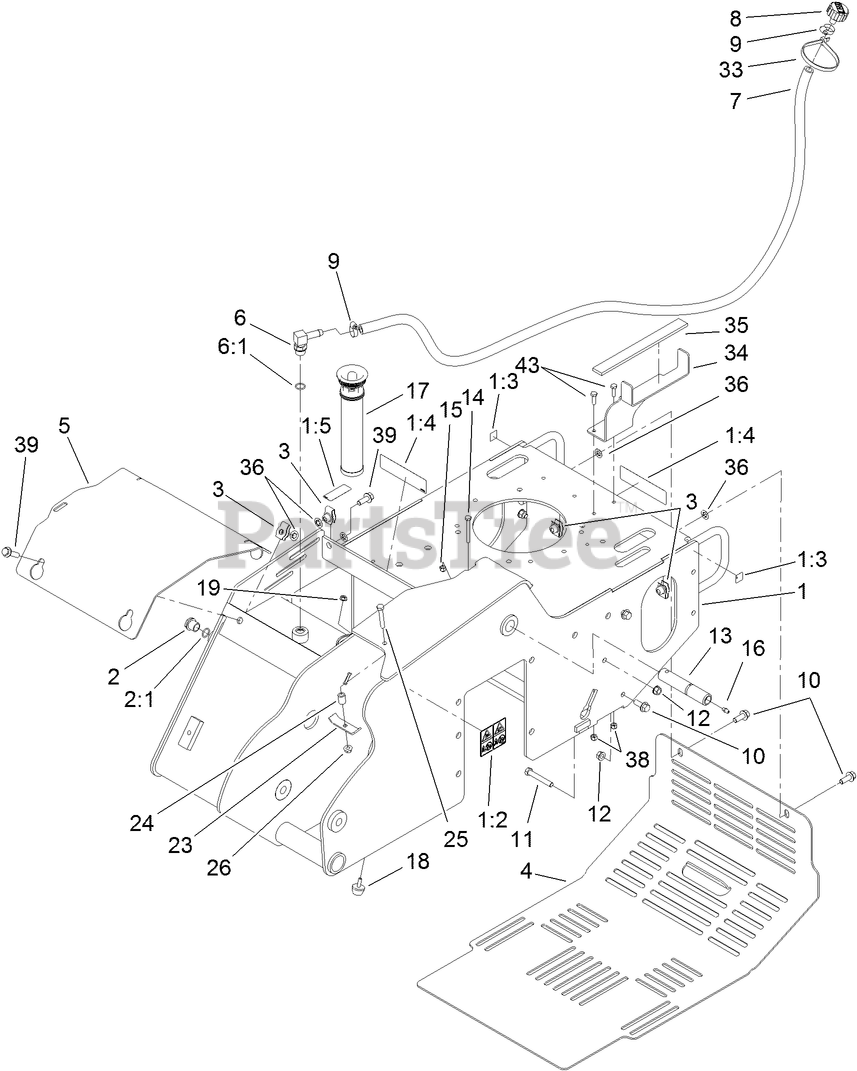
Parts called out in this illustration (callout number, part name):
1	MAIN FRAME ASM
1:2	DECAL-WARNING
1:3	DECAL-POINT, LIFT
1:4	DECAL-DANGER
1:5	DECAL-OIL, HYD
2	SIGHT GLASS ASM
2:1	O-RING
3	NUT-CLIP, U
4	COVER-REAR
5	PLATE-COVER, FRONT
6	FITTING-ELB 90
6:1	O-RING
7	HOSE-BREATHER
8	BREATHER
9	CLAMP-HOSE
10	SCREW-HHF
11	SCREW-HH
12	NUT-FLANGE
13	PIN-PIVOT
14	SCREW-HH
15	NUT-LOCK, NI
16	FITTING-GREASE
17	IN-TANK FILTER ASM
18	BUMPER
19	NUT-HF
23	BRACKET-CLAMP
24	SPACER
25	SCREW-HH
26	NUT-HF
33	TIE-CABLE
34	BRACKET-FUEL TANK
35	PAD-FOAM
36	NUT-PUSH
38	NUT-LOCK, NI
39	SCREW-HHF
43	SCREW-HH
